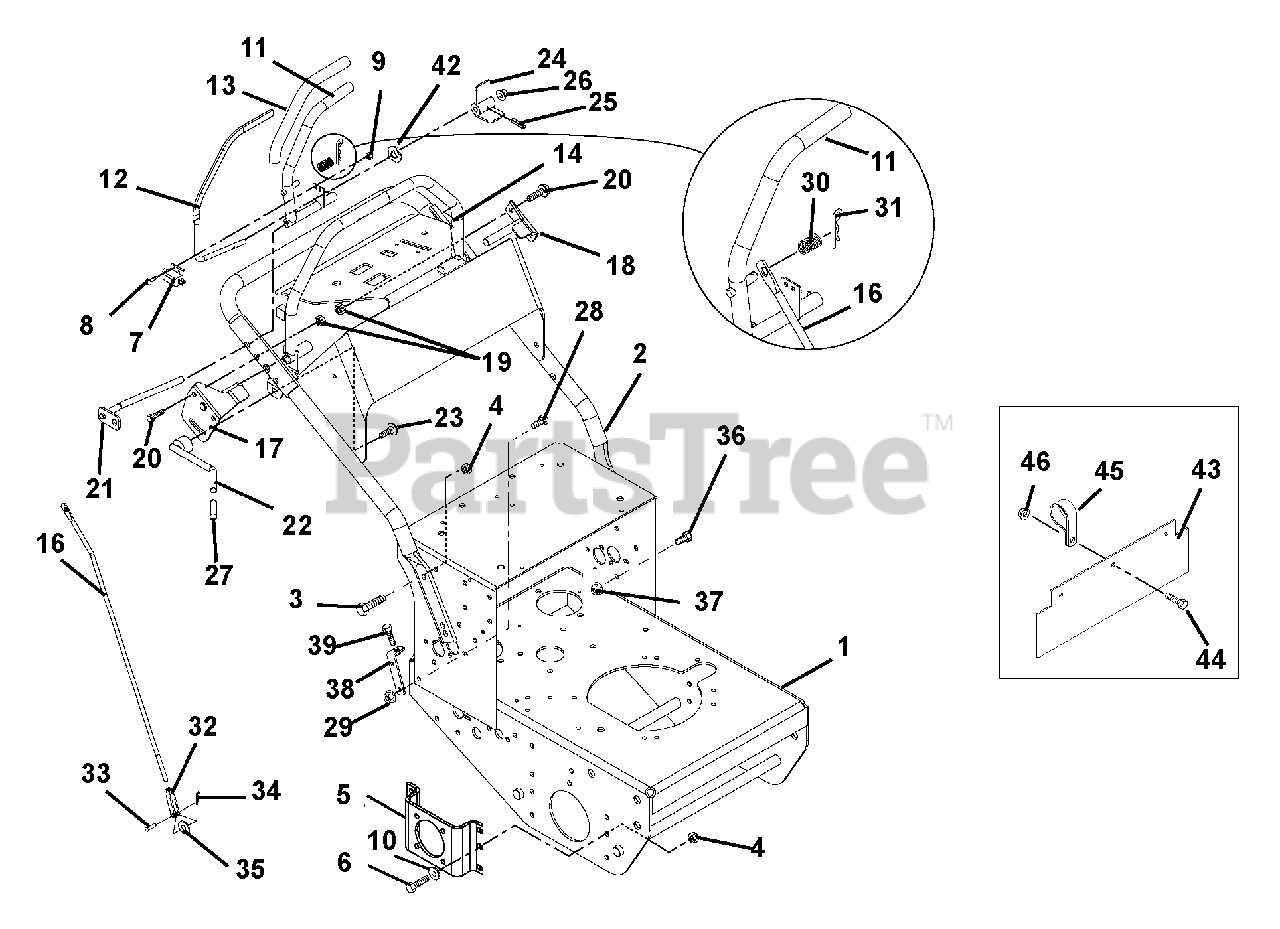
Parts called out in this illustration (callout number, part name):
1	KIT-FRAME W/DECALS
2	KIT-HANDLEBAR/DECALS HR15-ERGO
2	KIT-HANDLEBAR/DECALS HE17-ERGO
2	KIT-HANDLEBAR/DECAL GR13/15-PS
3	@BLT-HEX .38-16X1.00 GR5 YWZC
4	@NUT-LK-NYL .38-16 YWZC
5	BRACKET, WHEEL MOTOR LH
5	BRACKET, WHEEL MOTOR RH
5	BRKT, WHEEL MOTOR LH
5	BRKT, WHEEL MOTOR RH
5	PLATE, SUPPORT
6	@BLT-HEX .38-16X1.00 GR5 YWZC
7	SWITCH- DOUBLE POLE N.O./N.O.
7	SWITCH- SINGLE POLE N.O.
7	SWITCH,INTERLOCK
8	@SCR-MCH 10-24X.75 HWH YWZC
9	@NUT-LK-NYL 10-24 W/INSRT YWZC
10	@WSHR-FL-STL.406X.812X.065 YWZ
11	WMT-LEVER-RH SPEED CONTROL-HYD
11	WMT-LEVER-LH SPEED CONTROL-HYD
11	WMT-LEVER-RH SPEED CONTROL-GR
11	WMT-LEVER-LH SPEED CONTROL-GR
12	LEVER - OPERATOR PRESENCE
13	GRIP - HANDLEBAR
14	WMT - SPEED CONTROL STOP
16	ROD - STEERING - HYDRO
16	ROD - STEERING
17	WMT-CONTROL STOP LIMITER-RH
17	WMT - CONTROL STOP LIMITER -RH
18	WMT-CONTROL STOP LIMITER-LH
19	@NUT-LK-TOP-FLG .31-18 YWZC
20	@BLT-HEX .31-18X1.75 GR5 YWZC
21	WMT - SPEED CONTROL PIVOT - RH
21	WMT - SPEED CONTROL PIVOT - LH
22	LEVER - CONTROL STOP LOCK
23	BLT-RDHDSQSHK.31-18X.75 GR2 YW
23	@BLT-RDHDSQNK .38-16X.75 G5YZ
24	ACTUATOR - SWITCH
25	PIN-ROLL .125X.75
26	NUT-PUSH .312
27	GRIP,HAND CLUTCH LEVER
28	@BLT-HEX .38-16X.75 GR5 YWZC
29	@NUT-LK-TOP-FLG .38-16 YWZC
30	SG-COMP .045X.600X.750 WLD7.5
31	PIN-HAIR INT .08X.18X1.18 YWZC
32	YOKE, .312-24 X 2.25
33	PIN-CLEV .31X.937 FLHD YWZC
34	PIN-HAIR, ENDRIES #25 YWZC
35	WSHR-FL-STL .328X.87X.179 YWZC
36	@BLT-HEX .31-18X1.00 GR5 YWZC
37	@NUT-SPNLK-FLG .312-18 YWZC
38	WMT - REVERSE ADJUST BRACKET
39	@BLT-HEX .31-18X1.25 GR5 YWZC
42	WAVE WASHER .390X.655X.110
43	GUARD - DEBRIS
44	@BLT-HEX .38-16X.75 GR5 YWZC
45	CLAMP, COUSHIONED STEEL REV
46	@NUT-LK-TOP-FLG .38-16 YWZC
